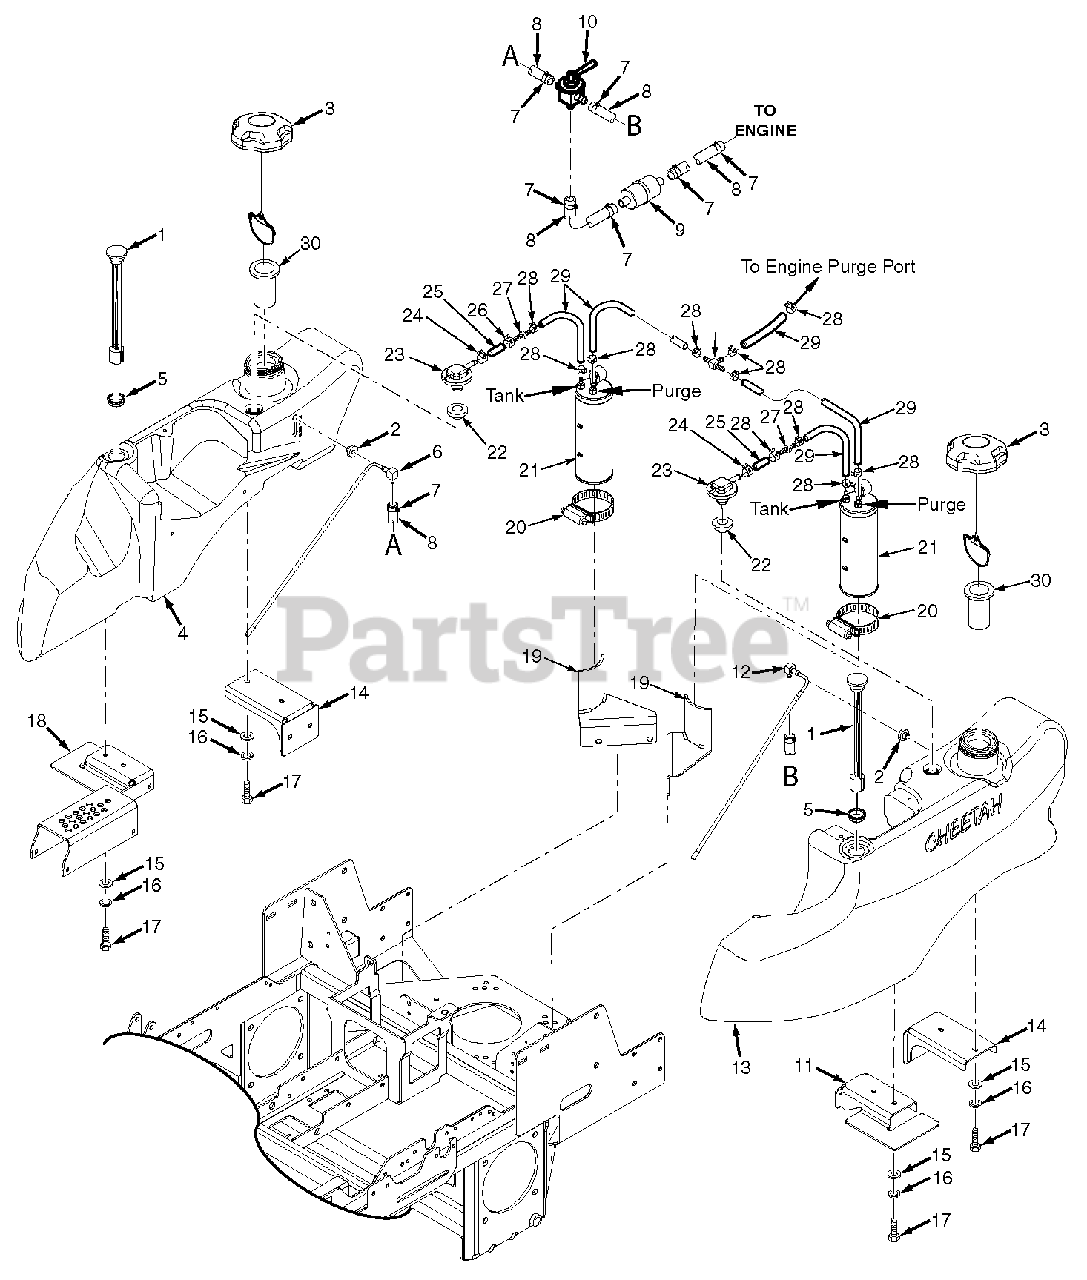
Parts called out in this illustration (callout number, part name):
1	Fuel Gauge
2	Bushing, .56 Dia. Viton
3	Fuel Cap, Tethered
4	Fuel Tank Assembly, RH
5	Grommet
6	Fuel Tube Assembly, RH
7	Clamp, Fuel Hose 1/4" ID
8	Fuel Hose, 1/4" Non-Perm (order by inch)
9	Fuel Filter
10	Valve, Fuel Shut-Off
11	Mounting Bracket, Fuel Tank Front
12	Fuel Tube Assembly, LH
13	Fuel Tank Assembly, LH
14	Mounting Bracket, Fuel Tank Rear
15	Flatwasher, 5/16-.375 x .875 x .083
16	Lockwasher, 5/16" Spring
17	Bolt, Hex Head 5/16-18 x 3/4"
18	Adjustment Bracket, Upper Cut Height
19	Canister Mounting Bracket
21	Carbon Canister
21	Dust Filter, Carbon Canister
22	Grommet, Viton
23	Remote Vent
24	Clamp, Fuel Hose 7/32"
25	Hose, 1/4" Vapor Recovery (order by inch)
26	Clamp, Fuel Hose 7/32"
27	Mender, 1/4 x 3/16 w/.02 Hole
28	Clamp, Vapor Recovery Hose 3/16"
29	Hose, 3/16"
30	Tube, Fuel Tank Insert
